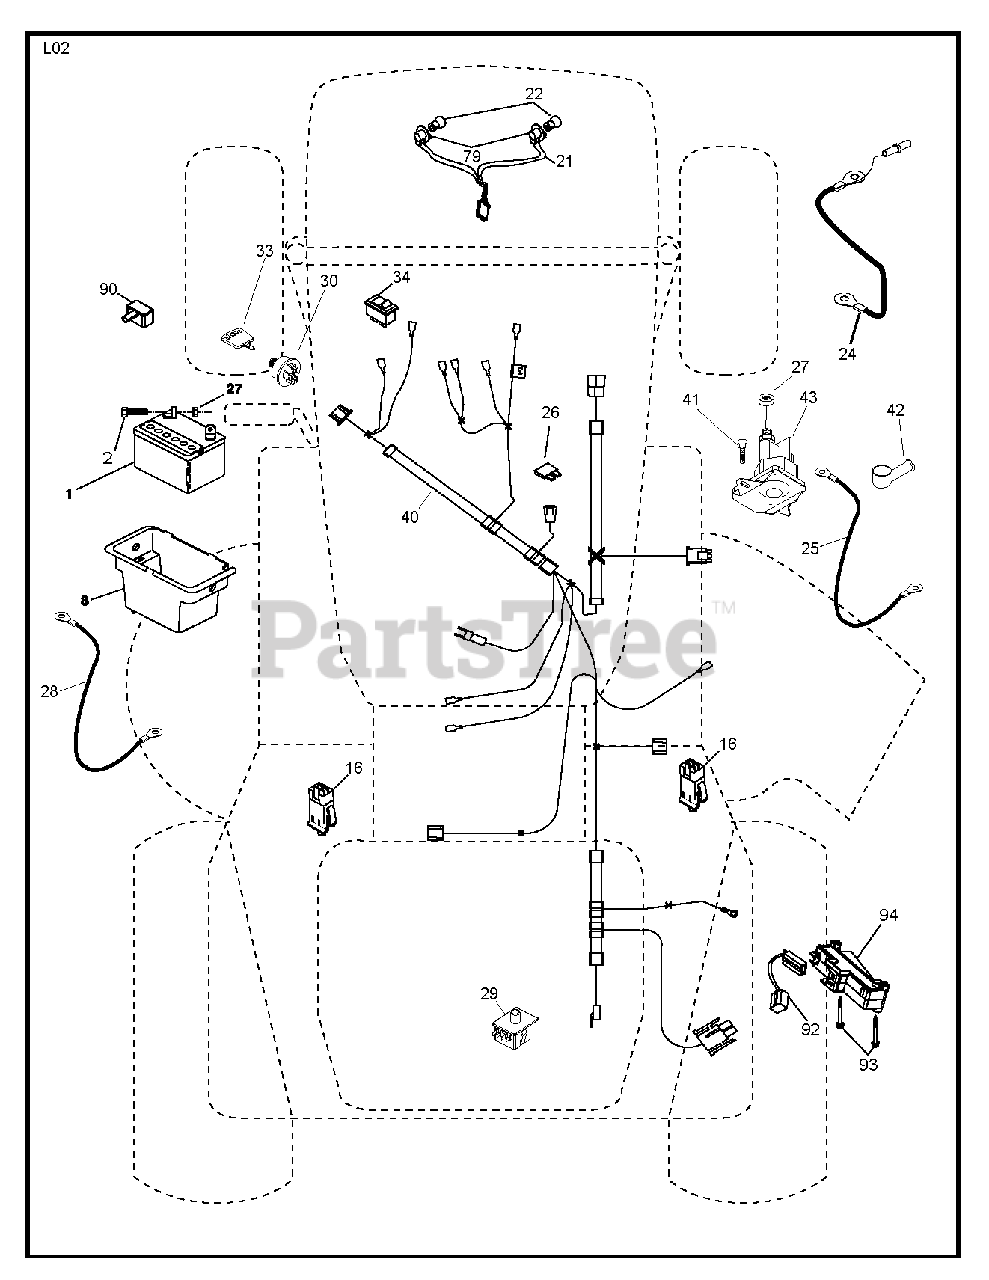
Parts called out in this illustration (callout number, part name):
1	REPL BY 532 12 38-99
2	BOLT.HEX.1/4.X.3/4.DICHROMATE
8	BOX.BATTERY.FENDER
16	SWITCH INTERLOOK PUSH-IN
21	HARNESS.W/LIGHT SOCKET
22	LIGHTBULB
24	CABLE.STARTER.6GA.11"RED
25	CABLE.GROUND.REAR.BTRY.8GA.44"
26	FUSE 20AMP
27	NUT
28	CABLE GROUND 6 GA. 12" BLACK
29	SWITCH.SEAT.DP W/RAMPS
30	SWITCH.IGN.DELTA.W.LGH.ROS
33	KEY.CHAIN.BLISTER.PACK.GEN.USA
34	SWITCH LT
40	HARNESS.IGN.CABLE.REG.
41	BOLT
42	TERMINAL COVER
43	SOLENOID.W/BRASS.PLUNGER
79	BULB HOLDER ASM.
90	COVER.TERMINAL.BATTERY
92	HARNESS.PIGTAIL.CONSLE
93	SCREW.PLASTITE
94	MODULE.REVERSE.ROS
